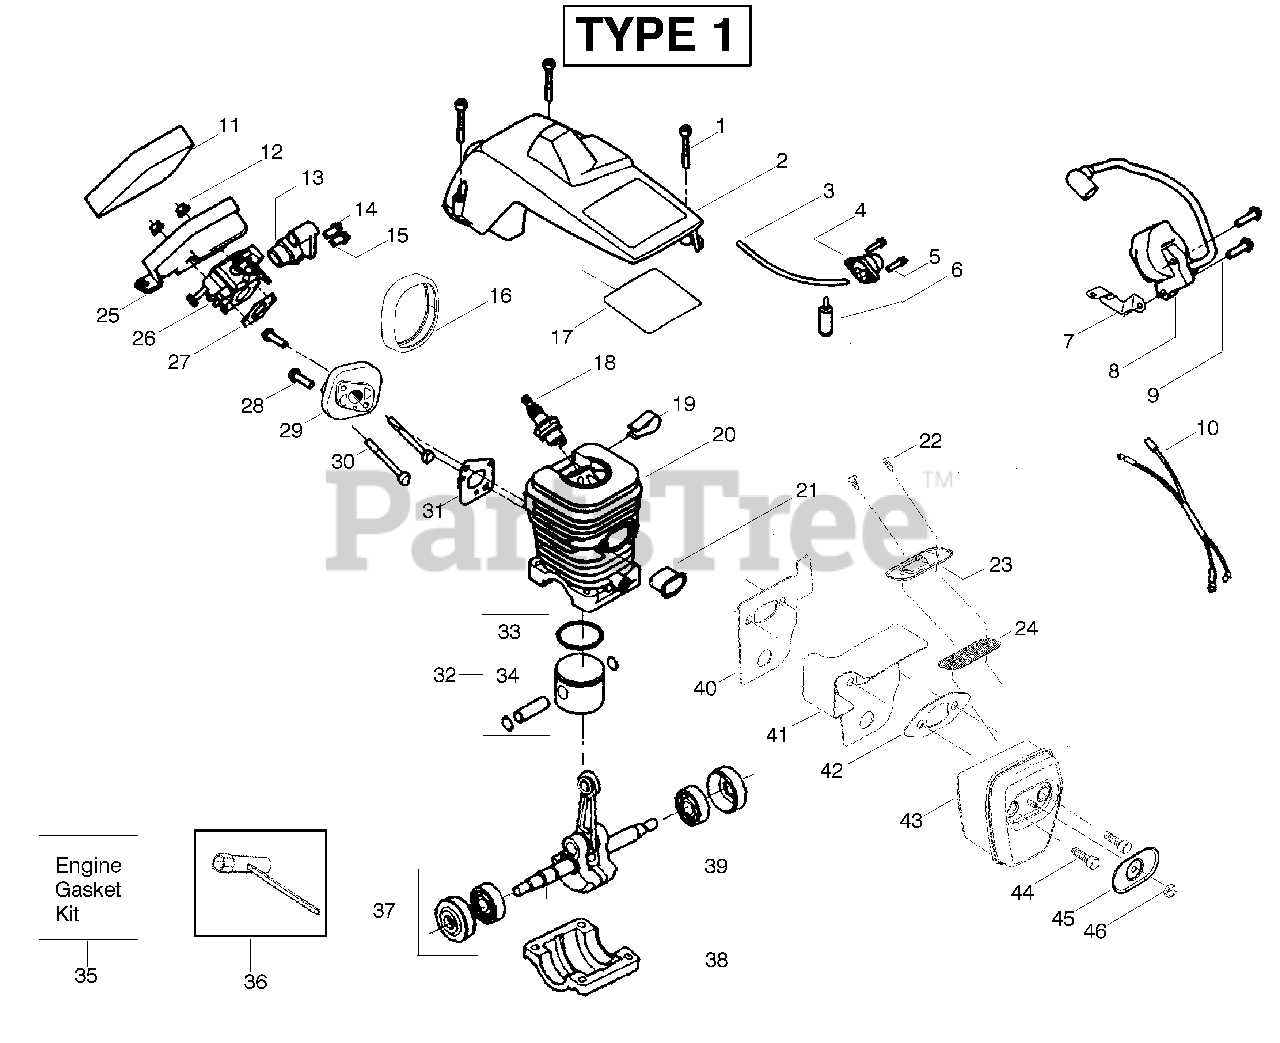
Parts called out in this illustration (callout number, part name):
2	Assy-Cylinder Shield
3	Kit-Fuel Line
4	Assy- Air Purge
6	Assy-Fuel Pick-up
7	Strap-Ground
8	Ignition Module
10	Assy-Wire Harness
11	Foam- Air Filter
13	Grommet-Carb Adjust
14	Limiter Cap-High
15	Limiter Cap-Low
16	Seal-Carb Adapter
17	Reflector-Heat
18	Spark Plug
19	Clip-High Tension Lead
20	Kit-Cylinder
21	Insulator-Heat
22	Screw-Outlet cover
23	Cover - Outlet
24	Kit-Spark Arrestor
25	Air Filter Housing
26	Kit-Carburetor (WT599)
27	Gasket-Carb.
28	Screw
29	Carb. Adapter
31	Gasket-Carb Adaptor
32	Kit-Piston
33	Ring-Piston
34	Retainer-Piston Pin
35	Kit-Engine Gasket
36	Bar Wrench
37	Assy-Seal & Bearing
38	Cap-Crankcase
39	Assy-Crankshaft
40	Backplate
41	Guide-Outlet
42	Gasket-Muffler
43	Assy-Muffler
44	Bolt-Muffler
45	Cover-Bolt
46	Nut-Brass
